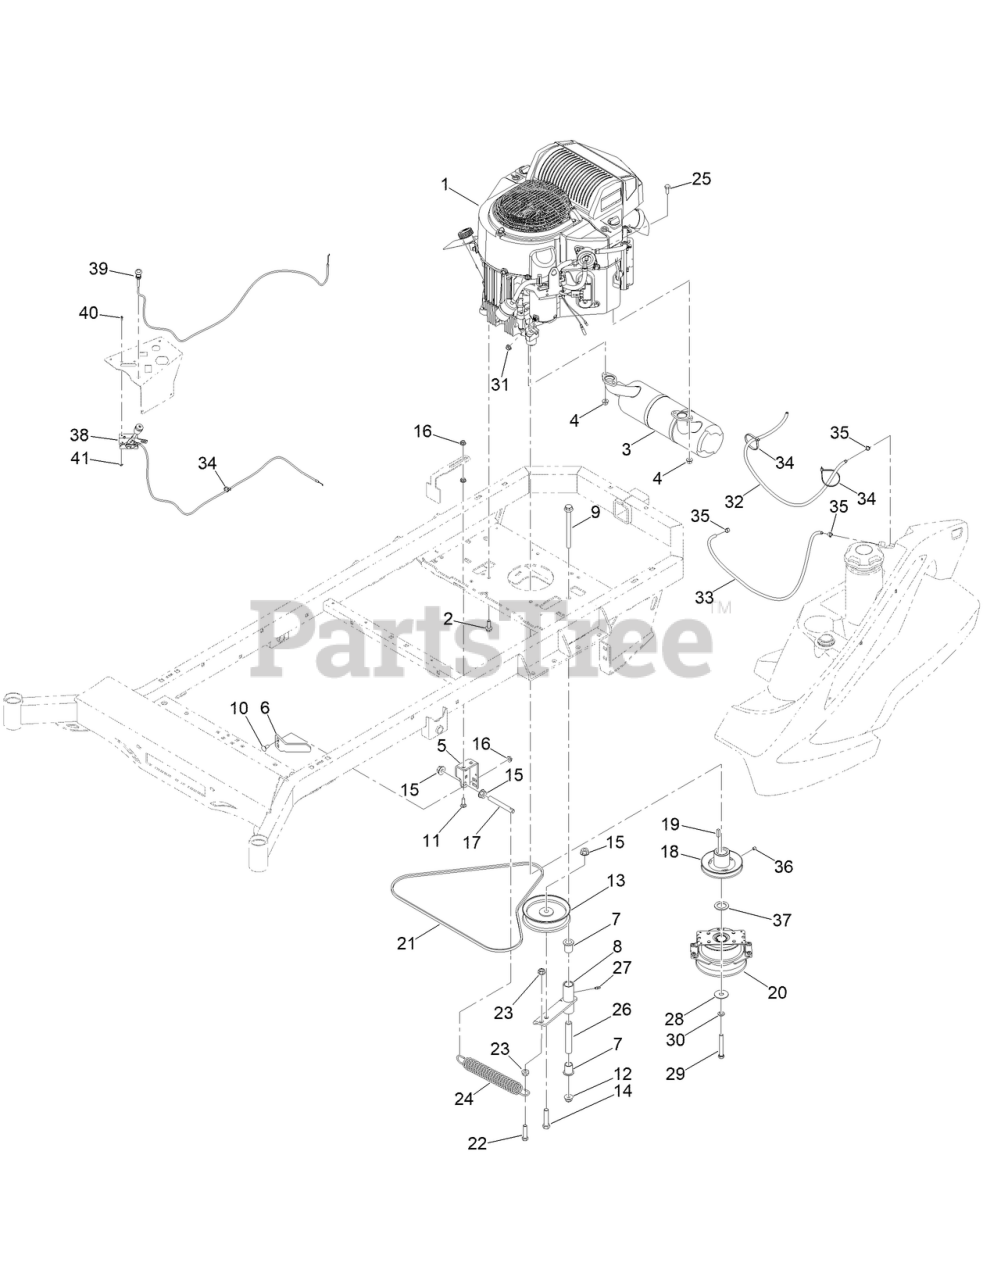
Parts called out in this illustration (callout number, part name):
1	KAWASAKI FR730V-DS27-R ENGN
2	3/8-16 X 1-1/8 IND HWH W/SERR TRI LOB ZY
3	2019 EXHAUST SYST FOR KAWI FR FS AND FT
4	NUT-HF
5	MWR PUMP IDLER TENSIONING BRKT BLACK
6	2021 TTQ MOWER OGURA CLUTCH BRACKET
7	3/4IN ID X15/16IN OD X 1-1/8IN FLNG BUSH
8	MWR PUMP IDLER ASSY BLACK
9	1/2-13 X 5-1/2 HEX FLANGE BOLT GR 8 ZY
10	BOLT-CARR
11	5/16-18 X 1-1/4 CARRIAGE BOLT ZC/YEL
12	NUT-LOCK
13	5-3/4IN IDLER PULLEY 7/16IN SPACER ASSY
14	SCREW-HH
15	NUT-HHF
17	MWR PUMP IDLER SPRING TENSIONER
18	MWR HYDRAULIC PUMP DRIVE PULLEYA BELT
20	MWR TTQ OGURA CLUTCH
21	MWR PUMP BELT RT A X 68.25IN EFF LNGTH
23	NUT-HF
24	MWR DECK SPRING
25	M8-1.25 X 20MM HEX FLANGE BOLT ZINC 10.9
26	MWR INNER IDLER SPACER
27	1/4IN DRIVE TYPE GREASE FITTING YZ
28	1/2IN X 1-5/8 BELLEVILLE CUP WASHER YZ
29	TTQ CLUTCH BOLT
30	WASHER-LOCK
31	1/4-20 HEX FLANGE NUT
32	MWR FUEL TANK BLACK 3/16IN VENT TUBE 1FT
33	1/4IN SAE J30R7 BULK HOSE 1FT
34	TIE-CABLE
35	1/2IN (#8) HOSE CLAMP
36	5/16-18 X 3/8 SOCKET SET SCREW
37	WASHER-THRUST
38	MWR THROTTLE CABLE ASSY W / HANDLE
39	MWR CHOKE CABLE ASSM
40	10-24 X 1/2 SOCKET C/S 18-8 SS
41	NUT-LOCK
